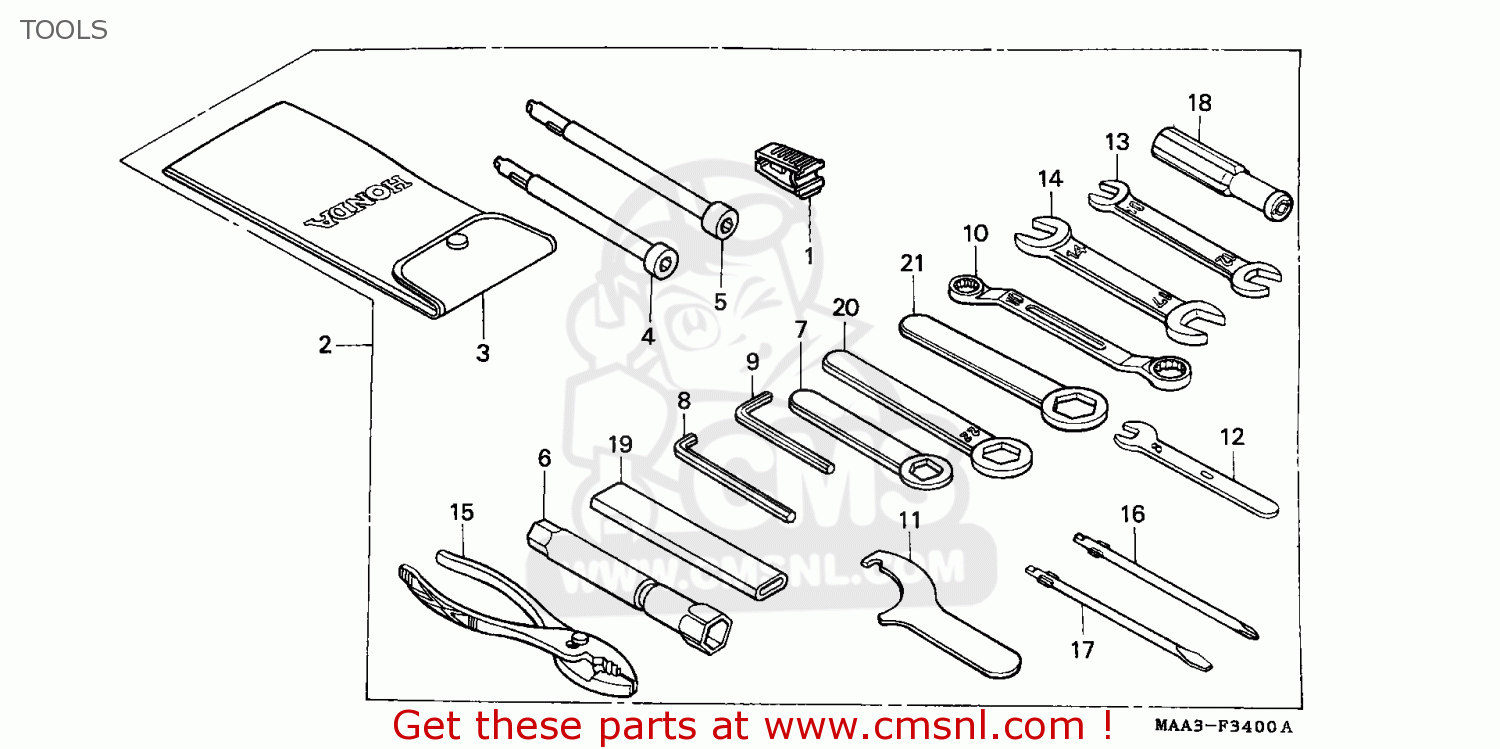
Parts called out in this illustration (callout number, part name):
2	TOOL SET
3	BAG,TOOL
4	WRENCH,BOX,8MM
5	WRENCH,BOX,10
6	WRENCH,PLUG
8	WRENCH 6,HEX.
9	WRENCH,HEX.,5MM
10	WRENCH,EYE,10X12
11	SPANNER,PIN
12	SPANNER, 8MM
13	SPANNER, 10X12
14	SPANNER, 14X17
15	PLIERS,135
16	DRIVER
17	SCREW DRIVER,3
18	GRIP,SCREW DRIVER
19	HANDLE,EYE WRENCH
20	EYE WRENCH,22
21	WRENCH,EYE,27MM
